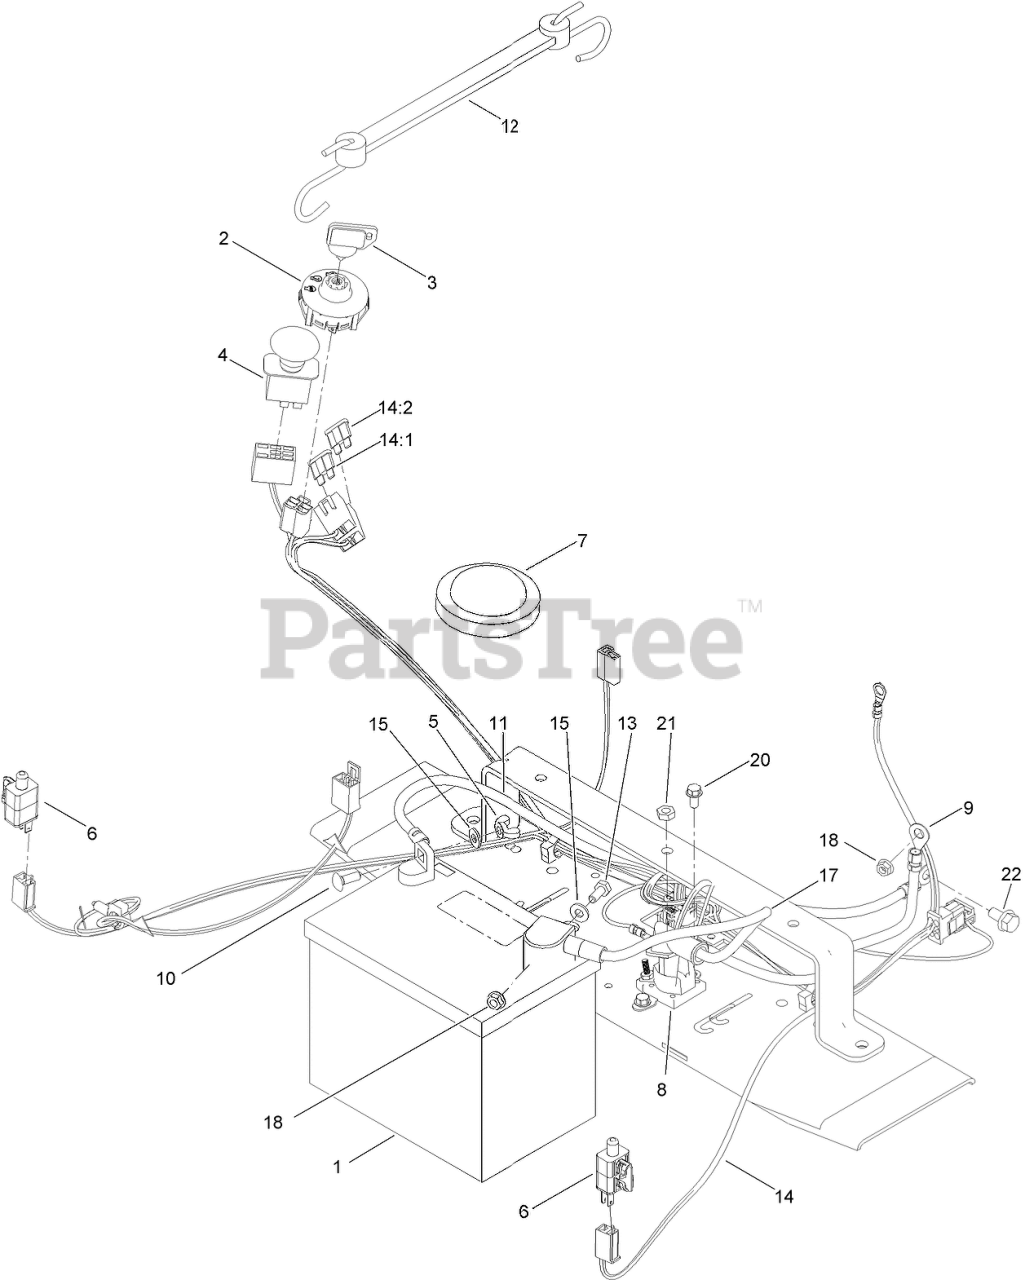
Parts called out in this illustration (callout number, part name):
1	BATTERY
2	SWITCH-IGNITION
3	KEY-IGNITION
4	SWITCH-PTO
5	NUT-WING
6	SWITCH
7	SWITCH-SEAT
8	SOLENOID
9	CABLE-BATTERY, RED
10	BOLT-CARR
11	CABLE-BATTERY, BLACK
12	HOLDDOWN-BATTERY
13	SCREW-HH
14	HARNESS-WIRE
14:1	FUSE-BLADE, 30 AMP
14:2	FUSE-BLADE, 25 AMP
15	WASHER-FLAT
17	CABLE-BATTERY, RED
18	NUT-HF
20	SCREW-HWH
21	NUT-JAM
22	SCREW-HHF
